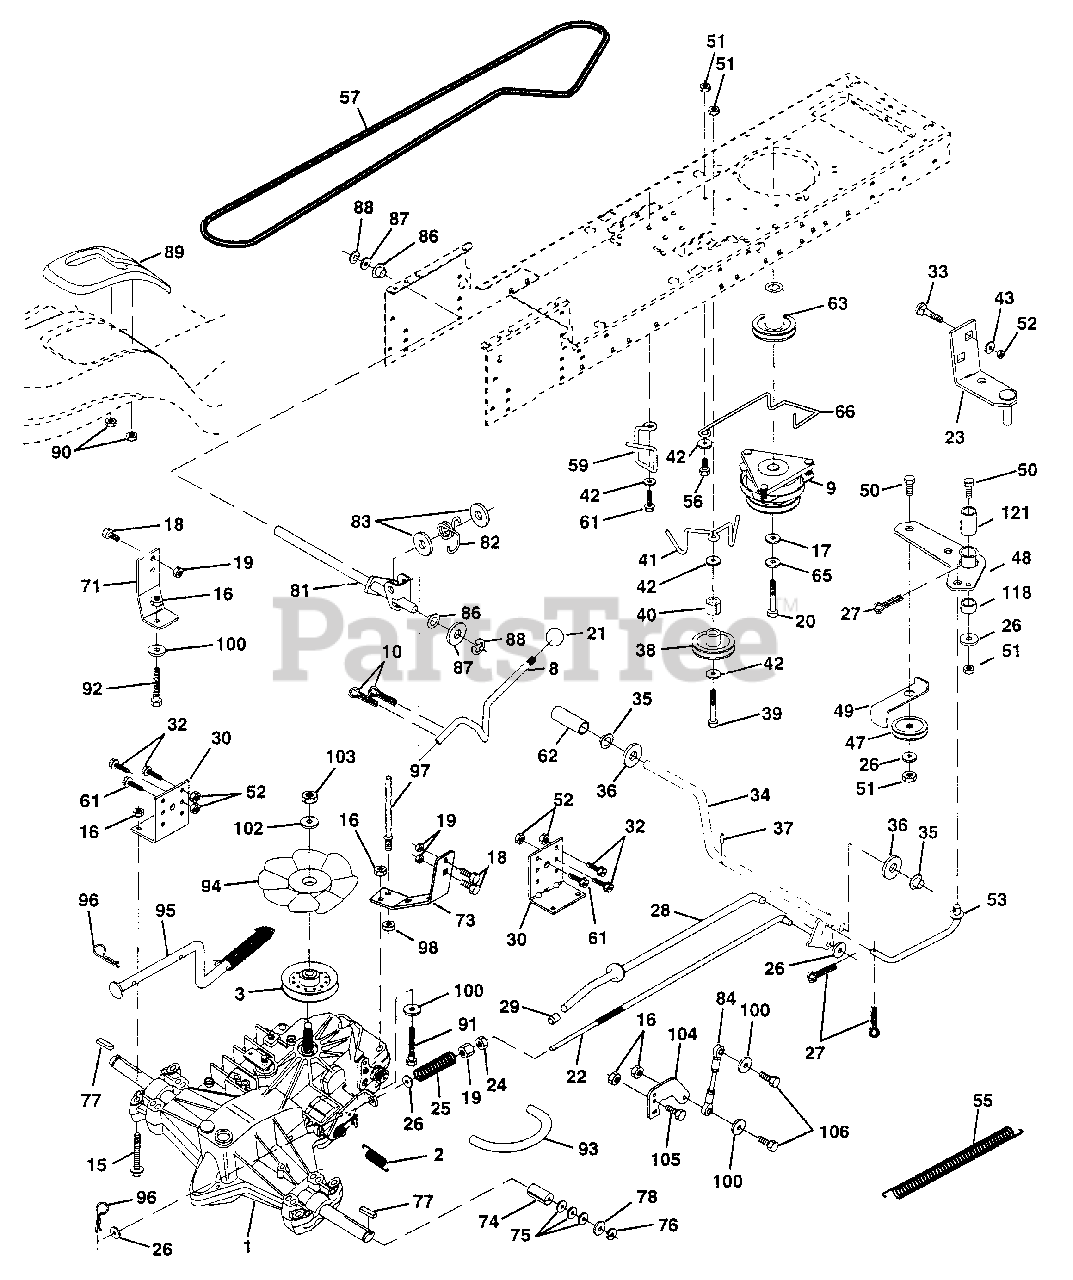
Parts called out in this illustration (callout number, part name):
1	Transaxle w/cas Hydro 310-0650
2	Spring, Return, Brake
3	Pulley, Transaxle Hydro 750 LT
8	Rod Shift STLT
9	Clutch Elecric
10	Pin Cotter 1/8 x 1 CAD
15	Bolt Hex 5/16-18 Unc Flghd
16	Nut Lock Hex W/Ins. 5/16-18 Unc P
17	Washer 1-1/2 OD x 15/32 ID x .250
18	Bolt Fin Hex 3/8-16 Unc x 1 Gr.5
19	Nut Lock Hex W/Ins 3/8-16 Unc
20	Bolt, Hex 7/16-20 x 4-1/4 Ga. 5
21	Knob Deluxe 1/2-13 UNC BLK/BLK
22	Rod, Brake Hydro
23	Bracket Asm Mtg CL
24	Nut Hex Jam 3/8-16 UNC
25	Spring, Brake Rod
26	Washer
27	Pin Cotter 1/8 x 3/4 CAD.
28	Rod, Parking Brake
29	Cap,Parking Brake
30	Bracket, Transaxle
32	Bolt Hex Hd 5/16-18 Unc x 3/4
33	Bolt Carriage 5/16-18 UNC x 3/4
34	Shaft, Foot Pedal
35	Bearing, Nylon
36	Washer
37	Pin, Roll
38	Pulley, Idler, Flat
40	Spacer Split
41	Keeper, Belt Idler
42	Washer 13/32 x 13/16 x 12 Ga
43	Washer 11/32 x 5/8 x 12 Ga.
47	Pulley, Idler, V-Groove Plastic
48	Bellcrank Assembly
49	Retainer, Belt Style Spring
50	Bolt
52	Nut Crown Lock 5/16-18
53	Link, Clutch
55	Spring, Return, Clutch
56	Bolt, Fin Hex 3/8-16 UNC x 1 1/4
57	V-Belt, Ground Drive
59	Keeper, Center Span
61	Screw Thdrol. 3/8-16 x 3/4 Ty. TT
62	Cover, Pedal Premium
63	Pulley, Engine
65	Washer Lock Hvy HLCL Spr 7/16
66	Keeper Belt Engine
71	Strap Torque Lh Hydro 18/20" T
73	Strap Torque Rh Hydro 0650
74	Spacer, Split
75	Washer 25/32 x 1-1/4 x 16 Ga.
77	Key, Square
78	Washer 25/32 x 1-5/8 x 16 Ga
81	Shaft Asm. Cross Hydro 20" Tires
82	Spring Torsion T/A
83	Washer 17/32 x 3/4 x 16 Ga.
84	Rod, Tie Hydro 20" Tires SPH Ball 4.75
86	Bushing Rod Strig. 629/632 ID
87	Washer 21/32 x 1-1/4 x 16 Ga.
88	Ring Klip #5304-62
89	Console, Hydro YT/GT Fender
90	Nut Self-Thd Wsh-Hd 1/4 Zinc
91	Bolt Fin Hex 5/16-18 x 2-1/4
92	Bolt Fin Hex 5/16-18 Unc x 1-1/2
93	Line Fuel Hydro 4"
94	Fan, Hydro 7"
95	Control Asm. Bypass Hydro
96	Retainer Spring 1" Zinc/Cad
97	Keeper Belt Rh Hydro 0750.18/20"
98	Nut Keps Hex 3/8-16 Unc
100	Washer 11/32 x 3/4 x 16 Ga.
102	Washer Belleville .501 D x 1.50D
103	Nut Hex Jam Toplock 1/4-20 Unf
104	Arm, Control Hydro
105	Screw Cap Hex 5/16 x 18 x 1
106	Bolt Fin Hex 5/16-18 Unc x 1-1/4
118	Spacer Bellcrank
121	Nyliner Clutching STL
